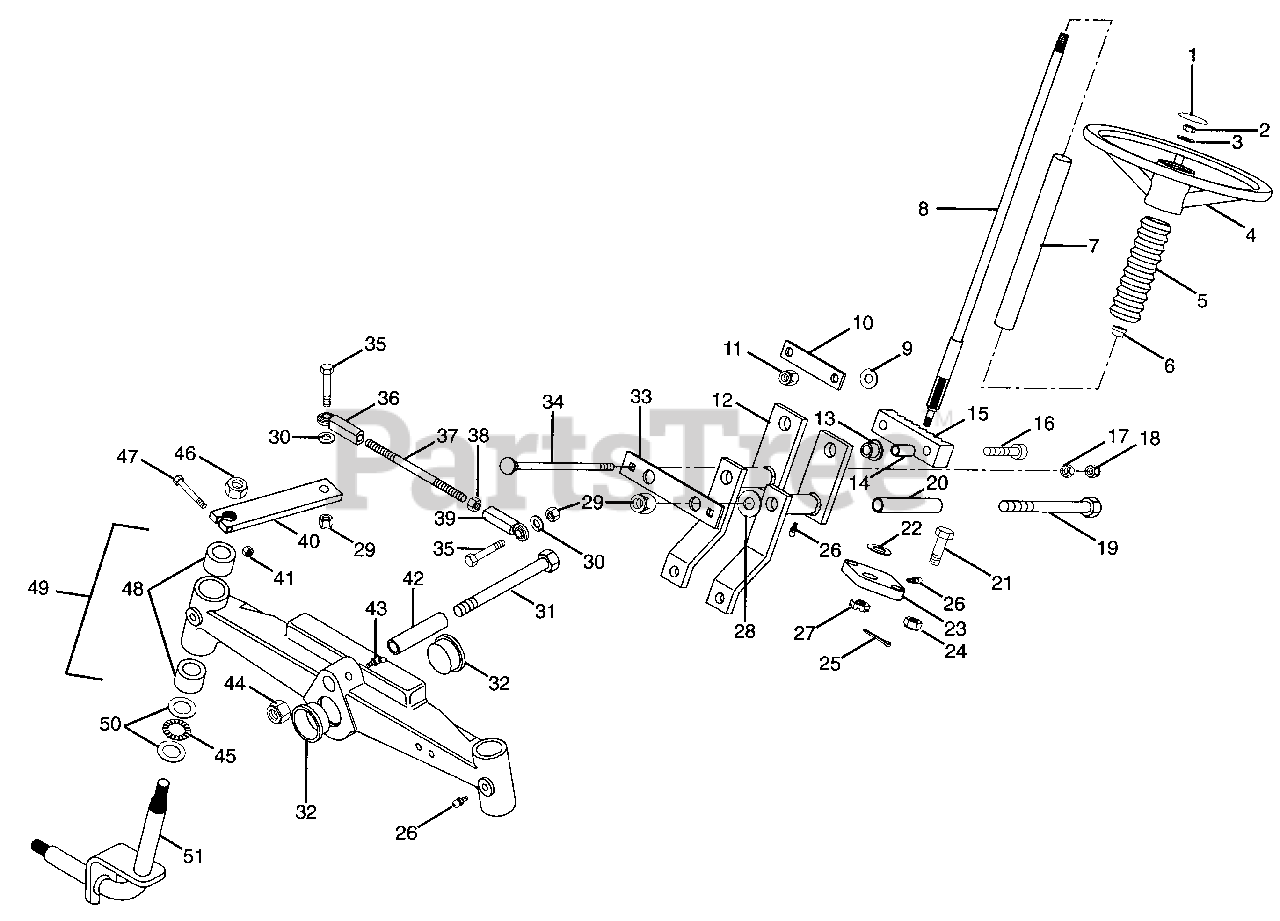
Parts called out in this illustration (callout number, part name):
1	Steering Wheel Cap
2	Nut-Jam .625-11
3	Washer-Flat-Steel .656 1.312 x .095
4	Steering Wheel
5	Steering Column Boot
6	Bushing-Flange .762 x 1.0 x .580 x 1.48
7	Tube-Plastic 1.0 I.D.
8	Weldment-Steering Shaft
9	Washer-Flat-Steel .38 x .875 x .083
10	Strap-Rack and Pinion
11	Nut-Locking-Center .375-16 Grade 2
12	Weldment-Steering
13	Bushing-Flange .627 x .879 x .469 x 1.120
14	Bushing-Steel .391 x .621 x .676
15	Grade-Rack
16	Bolt-Hex .38-16 x 2
17	Nut-Hex .312-18 Grade 2
18	Nut-Locking-Center .312-18 Grade 2
19	Bolt-Hex .50-13 x 6.00
20	Sleeve-Pivot
21	Bolt-Hex .44-14 x 1.50
22	Washer-Thrust .507 x .917 x .031
23	Support-Steering Shaft
24	Nut-Locking-Center .44-14
25	Pin-Cotter .09 x 1.00
26	Fitting-Lube .25-28 x .256
27	Nut-Hex-Slotted .500-13
28	Bearing-N-Thrust .752 x 1.24 x .093
29	Nut-Locking-Nylon .375-24 Grade 2
29	Nut-Locking-Center .50-13 Grade 5
30	Washer-Lock .50 x .125
31	Bolt-Hex .75-10 x 4.50
32	Cap-Front Axle
33	Plate-Adjustment
34	Bolt-Round Head Square Neck .31-18 x 5.50 Grade 2
35	Bolt-Hex .50-13 x 2.25 Grade 5
36	Rod End-Steering Right Hand Thread
37	Tie Rod-Steering
38	Nut-Jam .50-20 Grade 2
39	Rod End-Steering Left Hand Thread
40	Arm-Tie Rod Axle
41	Nut-Locking-Center .312-24 Grade 2
42	Tube-Axle Pivot
43	Fitting-Lube 45 Deg.
44	Nut-Locking-Center .75-10 Grade 2
45	Bearing-Thrust .875 x 1.427 x .078
46	Nut-Hex .625-11 Grade 2
47	Bolt-Hex .31-24 x 1.75
48	Bushing-Sleeve .866 x 1.004 x 1.000
49	Axle-Steering
50	Washer-Thrust .877 x 1.427 x .032
51	Weldment-King Pin
